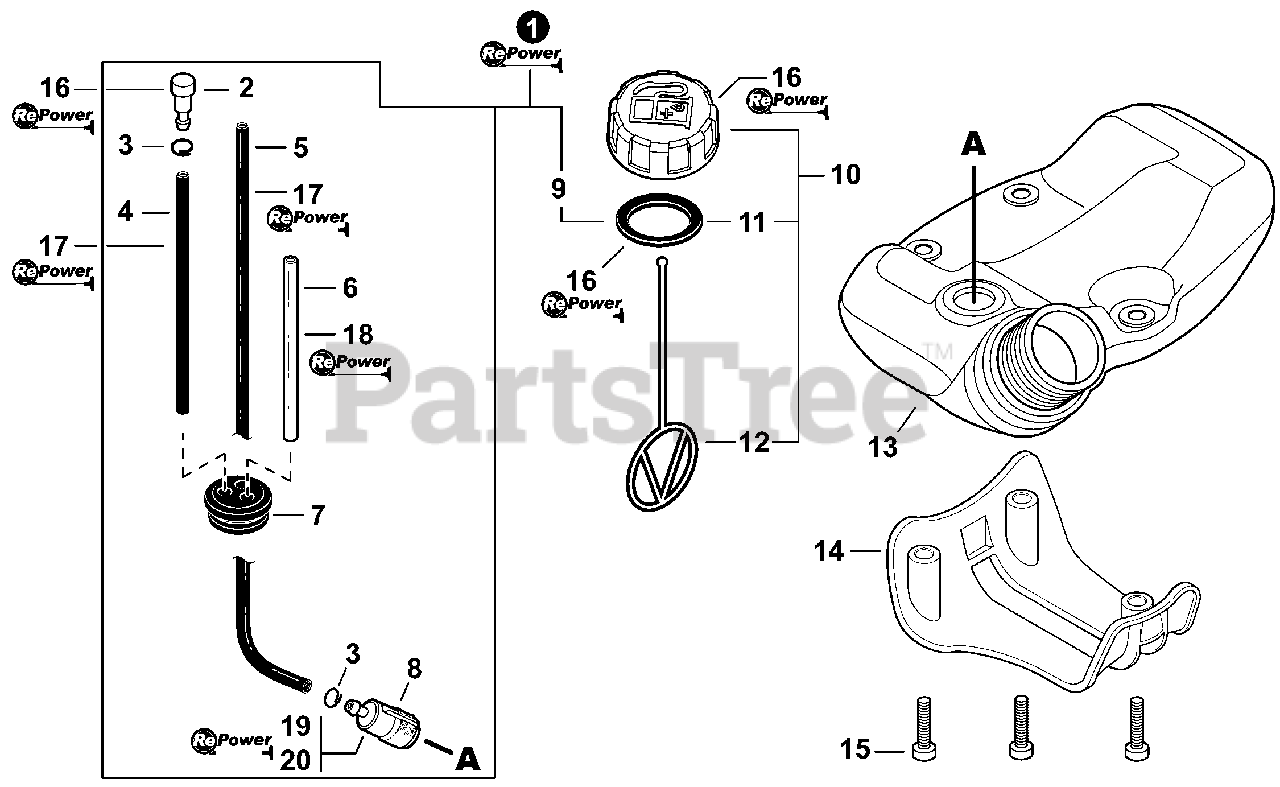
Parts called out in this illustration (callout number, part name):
1	FUEL SYSTEM KIT - REPOWER
2	VENT ASSY
3	CLIP 6MM
4	PIPE, FUEL 3×5×90 BLACK
5	PIPE, FUEL 3×5×210 BLACK
6	PIPE, FUEL 3×6×80 CLEAR
7	GROMMET, FUEL
8	FILTER, FUEL
9	GASKET, FUEL CAP
10	CAP ASSY, FUEL
11	GASKET, FUEL CAP
12	CONNECTOR, CAP L= 123
13	TANK, FUEL
14	GUARD, FUEL TANK
15	BOLT, TORX 5×25
16	CAP/VENT KIT - REPOWER
17	PIPE, BULK - REPOWER 3×5mm BLACK
18	PIPE, BULK - REPOWER 3×6mm CLEAR
19	TUNE-UP KIT - REPOWER
20	FILTER KIT - REPOWER
